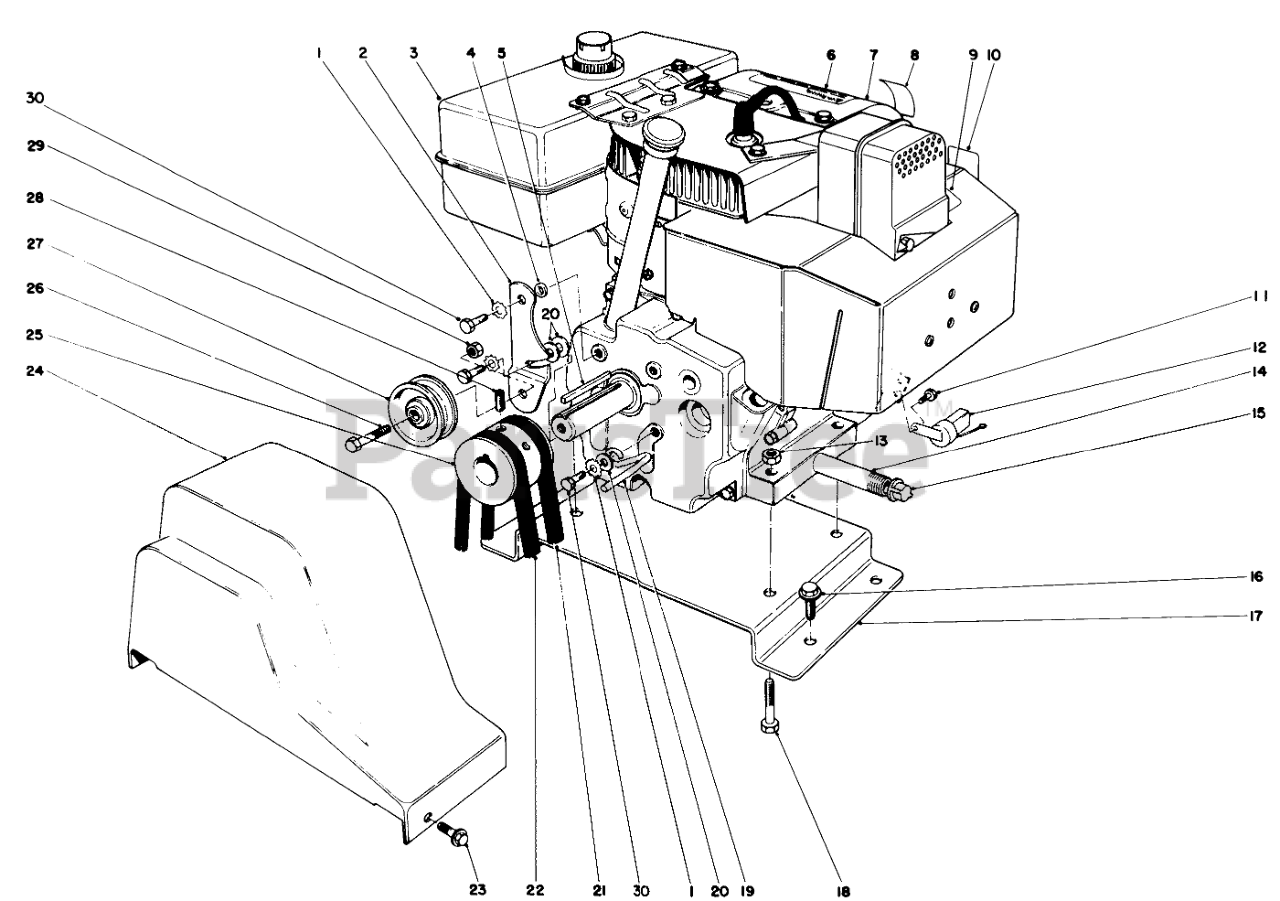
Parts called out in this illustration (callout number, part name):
1	WASHER-LOCK
2	ENGINE IDLER ARM
3	Fuel Tank w/Cap
4	SPACER
6	HAZARDS CAUTION DECAL
8	DECAL-PRIMER
9	DECAL-HOT SURFACE, WARNING
10	DECAL-CHOKE
11	SCREW-HWH
12	INTERLOCK MODULE
13	NUT-LOCK, NI
14	NIPPLE-PIPE
15	CAP-PIPE
16	SCREW-HWHTF
17	Plate ngine Mounting
18	SCREW-HH
19	BELT RETAINER
20	WASHER-PLAIN
21	V-BELT
22	V-BELT
23	SCREW-HWH
24	BELT GUARD
25	ENGINE PULLEY
26	SCREW-HH
27	PULLEY-IDLER
28	SETSCREW
29	NUT-LOCK, NI
30	SCREW-HH
